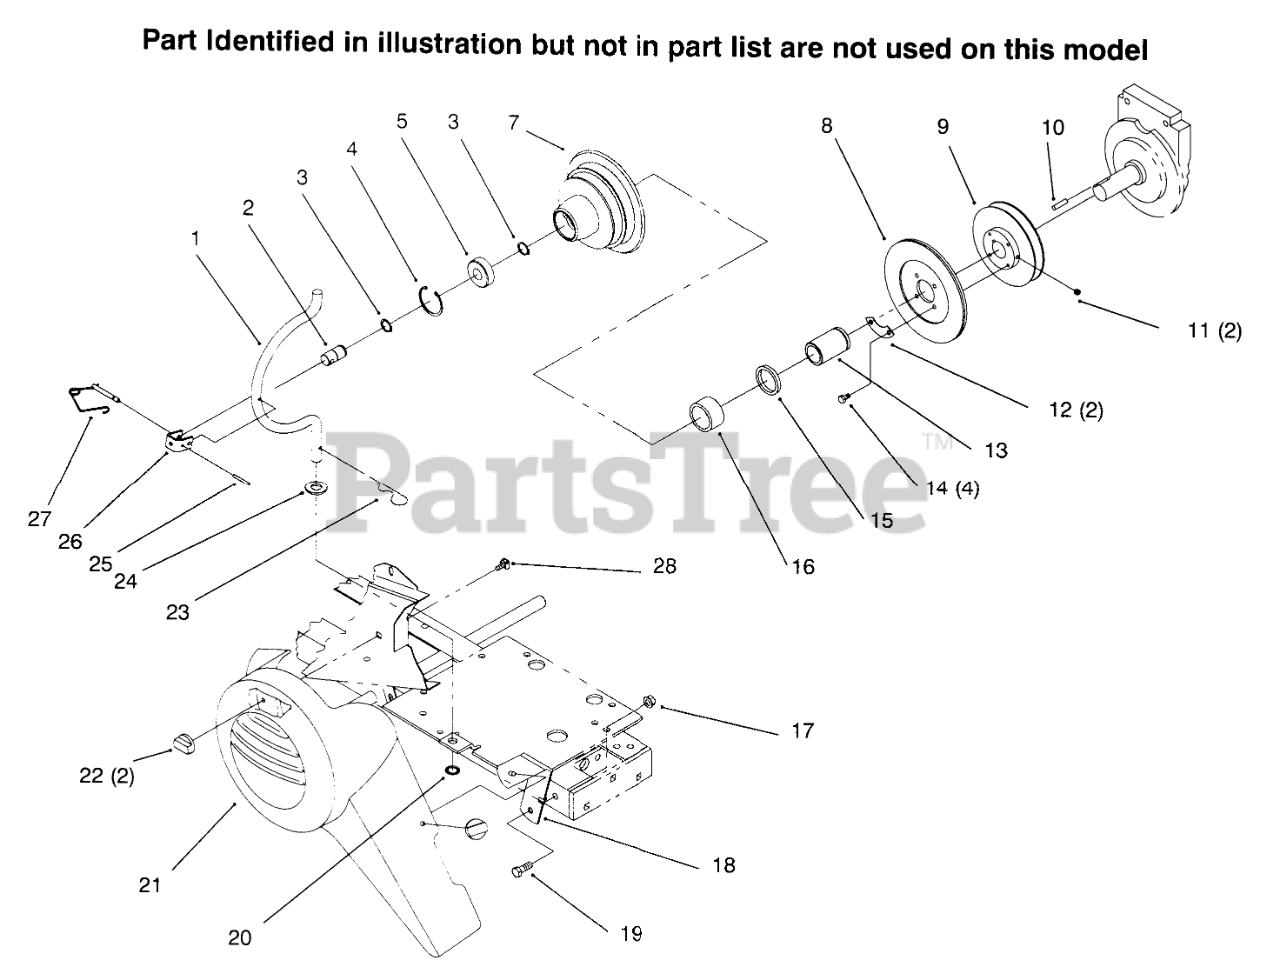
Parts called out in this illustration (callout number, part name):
1	ROD-HOUSING
2	SHAFT-PTO
3	Ring-Snap
4	RING-RETAINING
5	BEARING-BALL
7	Housing-Clutch
8	Facing-Clutch
8	ASS'Y-CLUTCH PLATE
9	PULLEY
11	SCREW-SET, HSH
12	RETAINER
13	RACE-BEARING
14	SCREW-HEX HD CAP
15	SEAL-OIL
16	Seal
17	NUT-FLANGE
18	Bracket
19	SCREW-HH
20	RING-REINFORCED CIRC
21	GUARD - BELT
22	NUT - WING
23	PIN-COTTER, HAIR
24	WASHER-FLAT
26	CLEVIS
27	LOCKING PIN ASM
28	Retainer-Bolt
